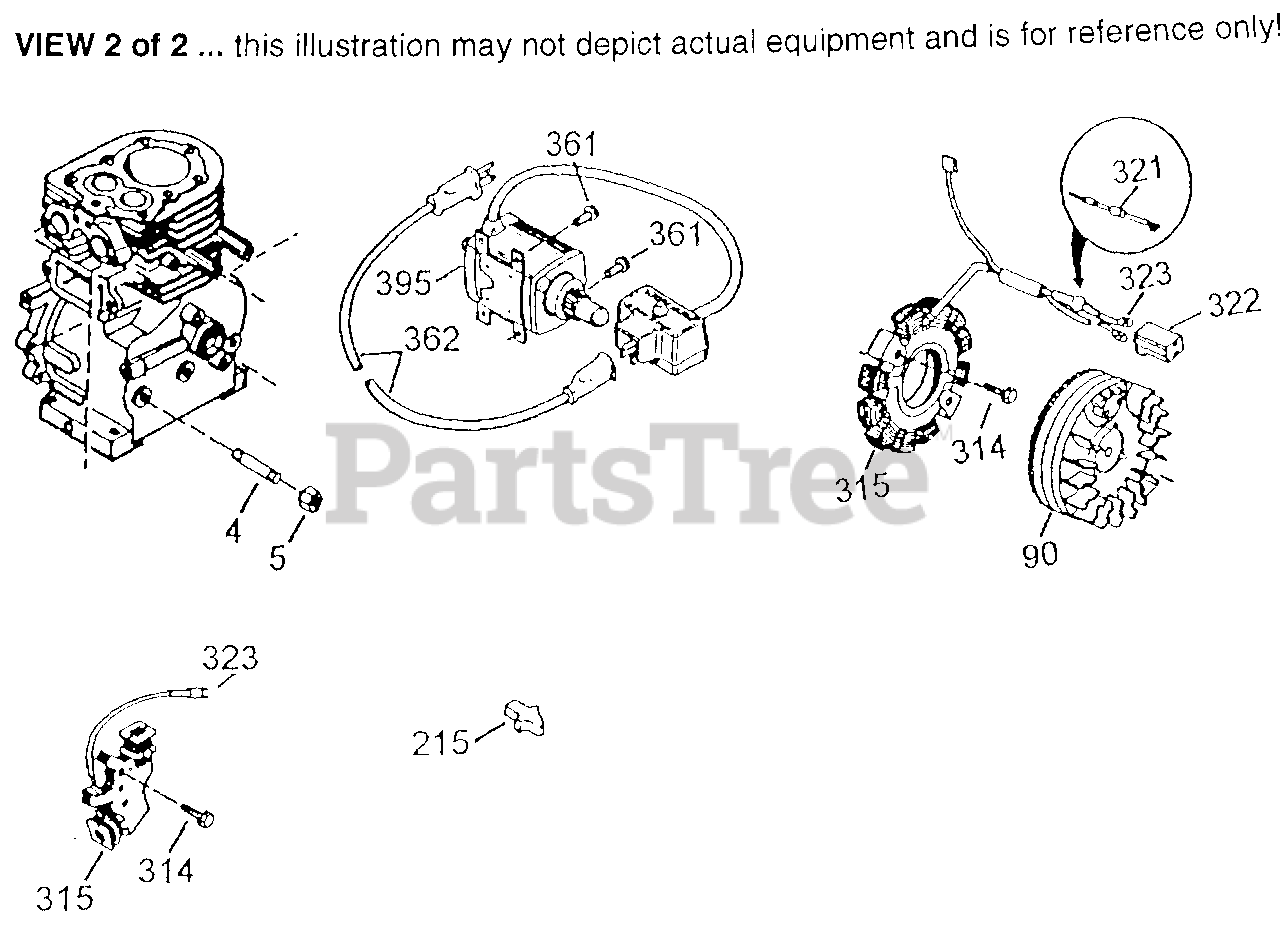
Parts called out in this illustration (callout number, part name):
4	Oil Drain Extension Purchase Locally
5	Extension Cap
90	Flywheel (W/Ring Gear)
186B	Choke Spring
215	Control Knob
314	Screw, 1/4-20 x 3/4"
315	Alternator Coil (18 Watt)(Incl. 323)
323	Terminal
336	Screw, 10-32 x 1/2"
396	Electric Starter Motor (Optional)
